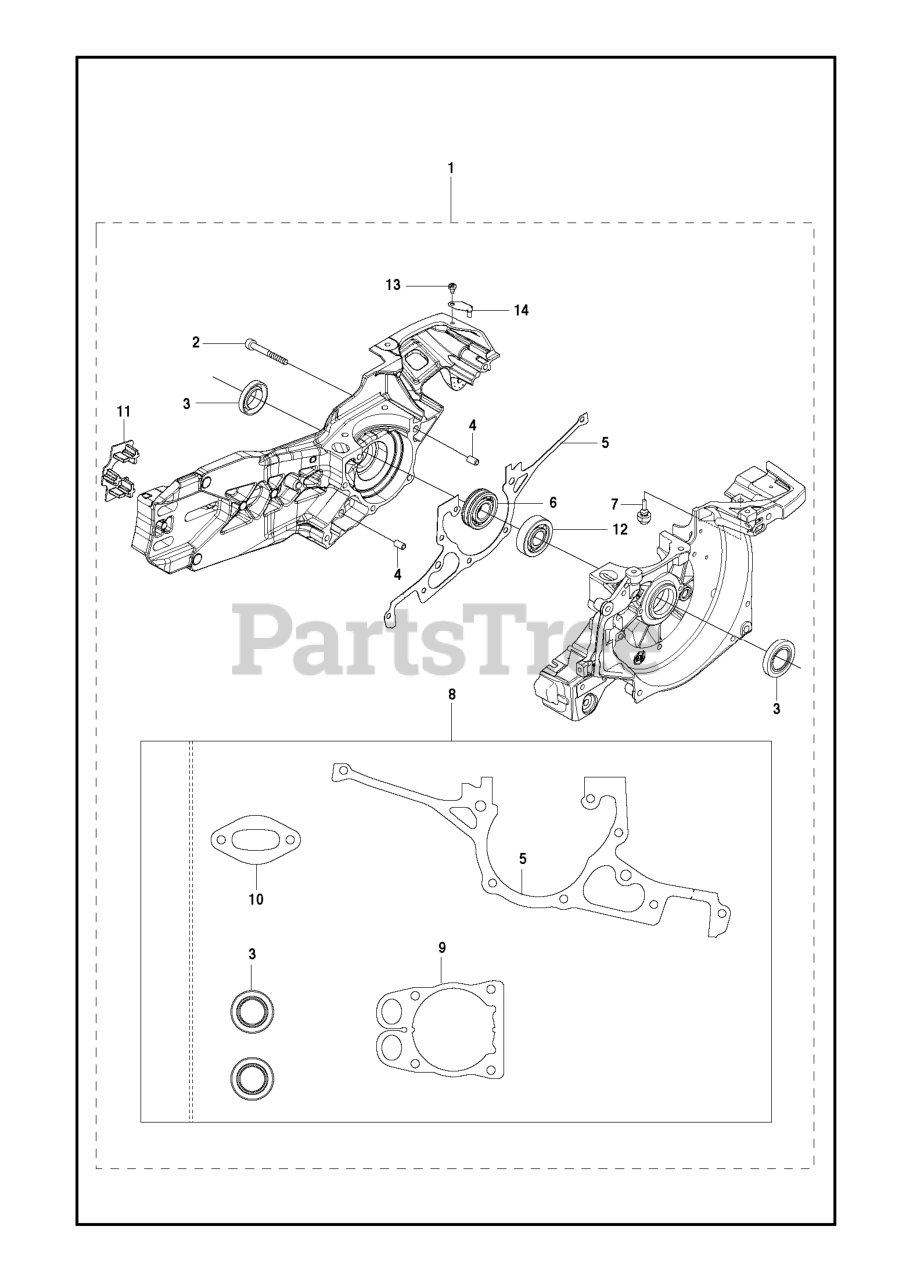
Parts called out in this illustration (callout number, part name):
1	CRANKCASE SPARE PART KIT
3	SEALING RING
5	GASKET CRANKCASE K970
6	BALL BEARING 6203 EC-C13/20-JR
7	RUBBER BUSHING
8	GASKET KIT K960 K970/K970-II/K
9	GASKET CYLINDER
11	RUBBER SHOE CONTACT ABSORBER
12	BALL BEARING 6203C3QE6
13	SCREW CITXPANT PW3.5X6.5 T10
14	WEAR PROTECTION CHOKE
